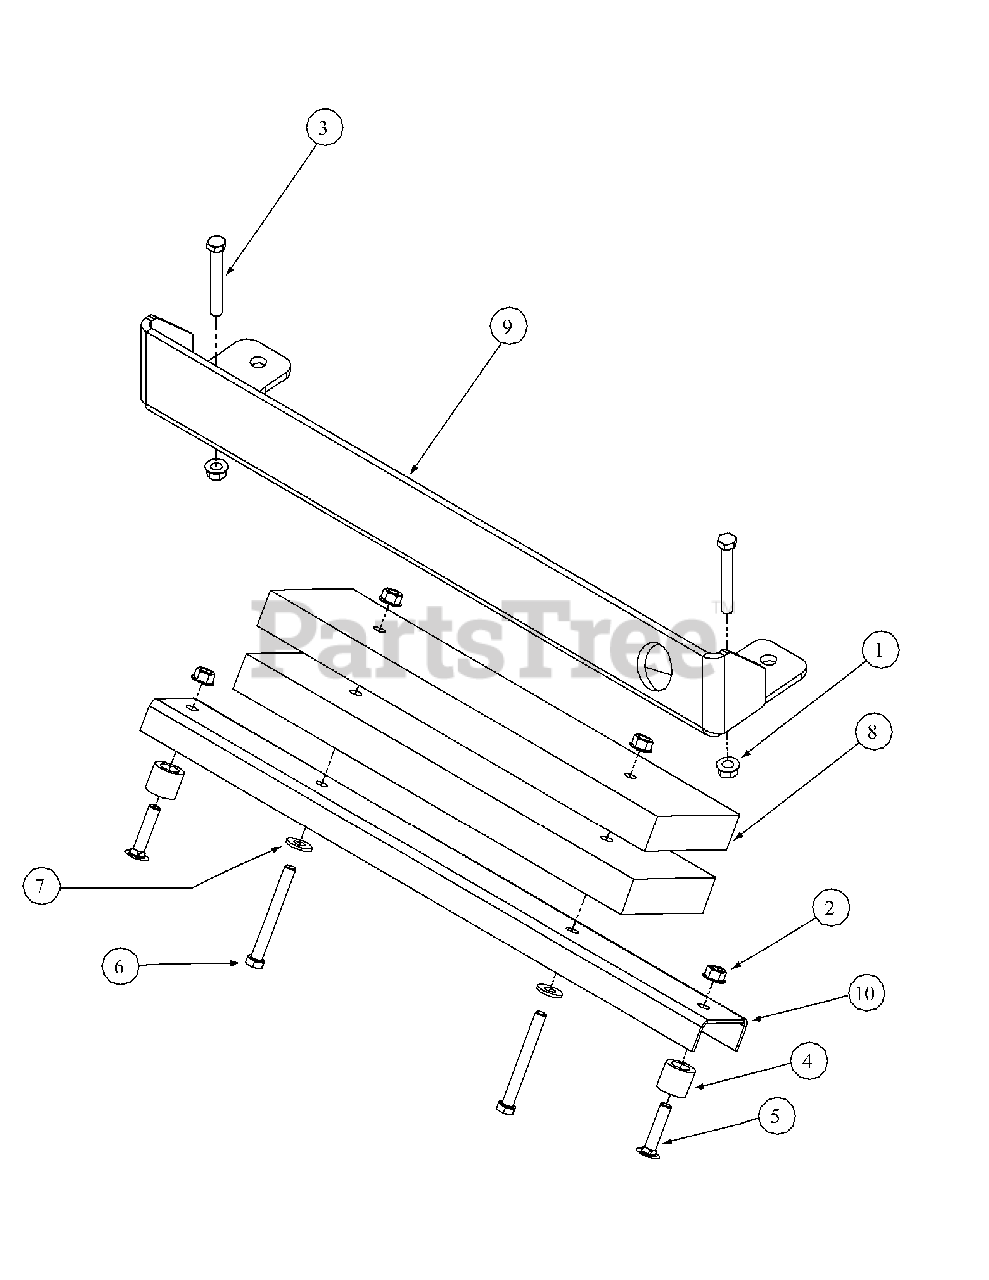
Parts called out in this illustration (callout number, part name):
1	Hex Nut, 1/2-13, Insert Lock
2	Nut, Hex 3/8-16 Flange Lock
3	HHCS, 1/2-13, 3.00
4	Spacer Crossbar
5	Carriage Bolt, 3/8-16, 1.75
6	HHCS, 3/8-16, 3.25
7	Flat Washer, .406 ID x 1.0 OD x .105
9	Rear Bumper Plate
10	Bumper Cross Bar-Rear
